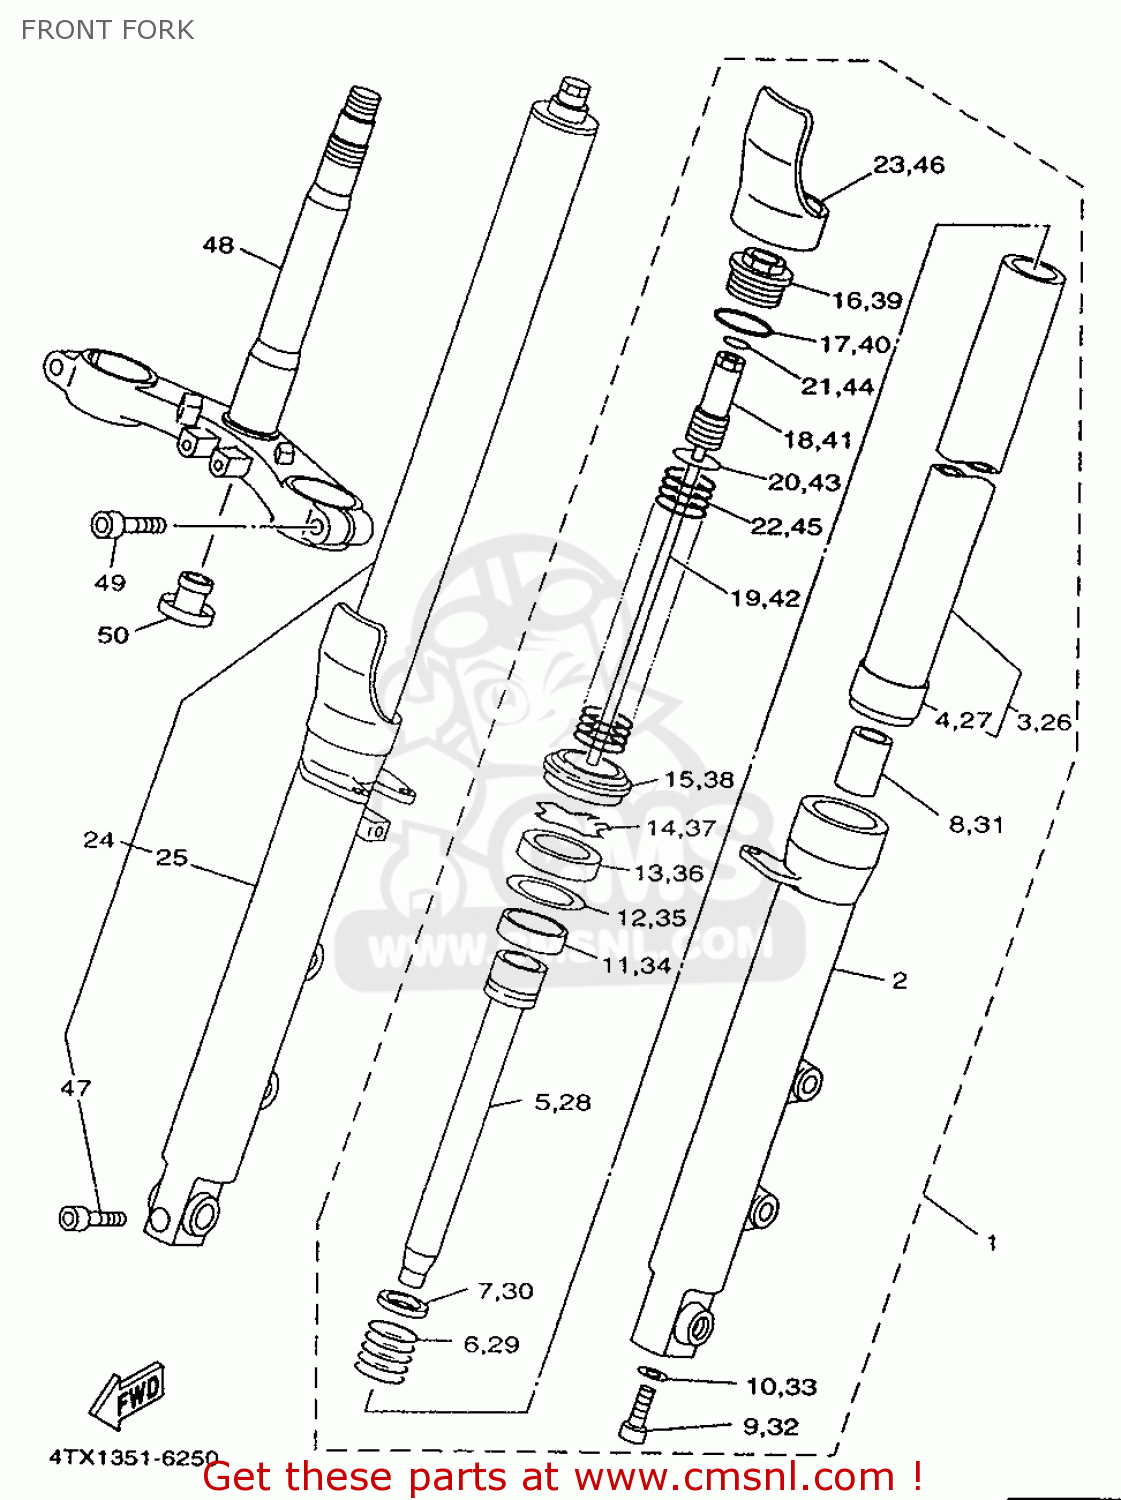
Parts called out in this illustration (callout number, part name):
01	FRONT FORK ASSY (L.H)
02	TUBE, OUTER (LEFT)
03	INNER TUBE COMP.1
04	METAL, SLIDE 2
05	CYLINDER COMP., FRONT FORK
06	SPRING, REBOUND
07	RING, PISTON
08	SPINDLE, TAPER
09	BOLT, SOCKET
10	GASKET (5R6) (NAS)
11	METAL, SLIDE 1
12	GUIDE, COVER UPPER
13	OIL SEAL
14	CLIP, OIL SEAL
15	SEAL, DUST
16	FORK, BOLT
17	O-RING (21A)
18	BOLT, SPRINGADJUST
19	PLUNGER KIT
20	SEAT, SPRING UPPER
21	O-RING(3VD)
22	SPRING, FRONT FORK
23	COVER
24	FRONT FORK ASSY (R.H)
25	TUBE, OUTER (RIGHT)
26	INNER TUBE COMP.1
27	METAL, SLIDE 2
28	CYLINDER COMP., FRONT FORK
29	SPRING, REBOUND
30	RING, PISTON
31	SPINDLE, TAPER
32	BOLT, SOCKET
33	GASKET (5R6) (NAS)
34	METAL, SLIDE 1
35	GUIDE, COVER UPPER
36	OIL SEAL
37	CLIP, OIL SEAL
38	SEAL, DUST
39	FORK, BOLT
40	O-RING (21A)
41	BOLT, SPRINGADJUST
42	PLUNGER KIT
43	SEAT, SPRING UPPER
44	O-RING(3VD)
45	SPRING, FRONT FORK
46	COVER
47	BOLT,SOCKET
48	UNDER BRACKET COMP.
49	BOLT, SOCKET
50	COVER, LOWER 1
